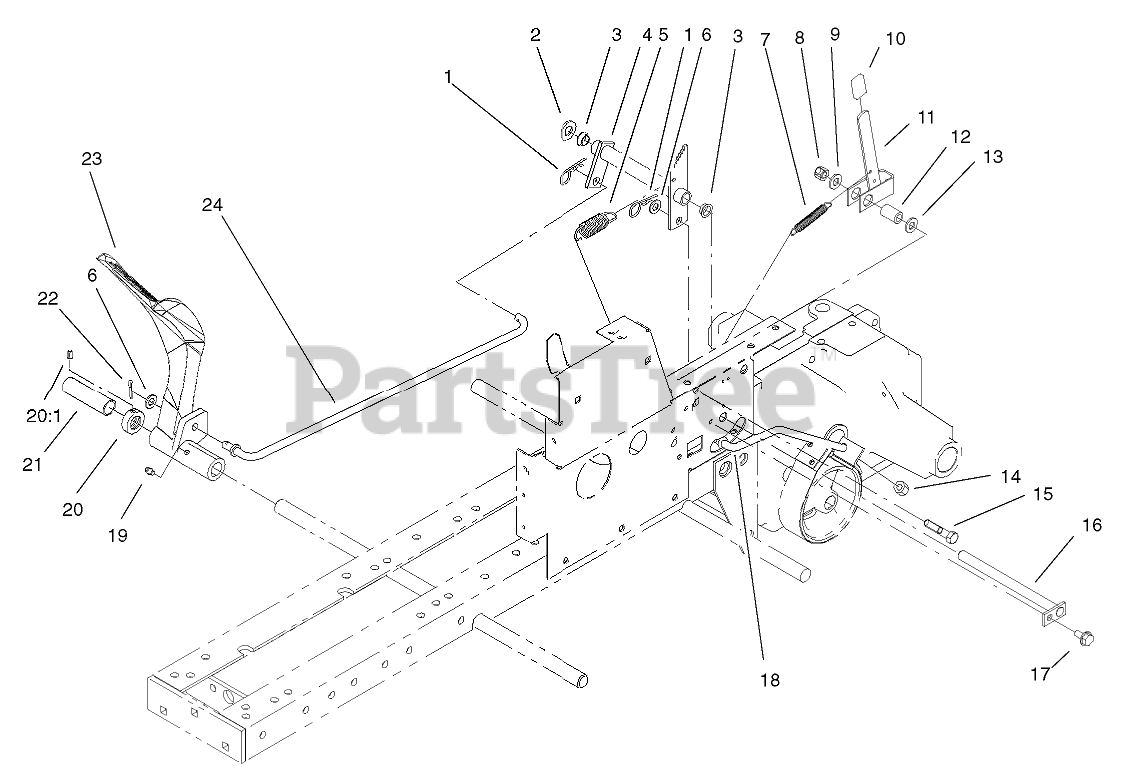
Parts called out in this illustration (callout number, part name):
1	PIN-HAIR
2	WASHER-FLAT
3	BUSHING-FLANGED
4	BELCRANK ASM
5	SPRING-EXTENSION
6	WASHER-NYLON
7	SPRING-BRAKE
8	NUT-LOCK, NI
9	WASHER-FLAT
10	GRIP
11	BRAKE LEVER ASM
12	SPACER
13	WASHER-FLAT
14	NUT-LOCK, NI
15	SCREW-HH
16	ROD ASM
17	SCREW-HWHTF
18	ROD-REAR BRAKE
19	FITTING-GREASE
20	COLLAR
20:1	SCREW-HSH
21	SLEEVE-PROTECTIVE
22	PIN-COTTER
23	PEDAL-BRAKE, GEAR
24	ROD-BRAKE
